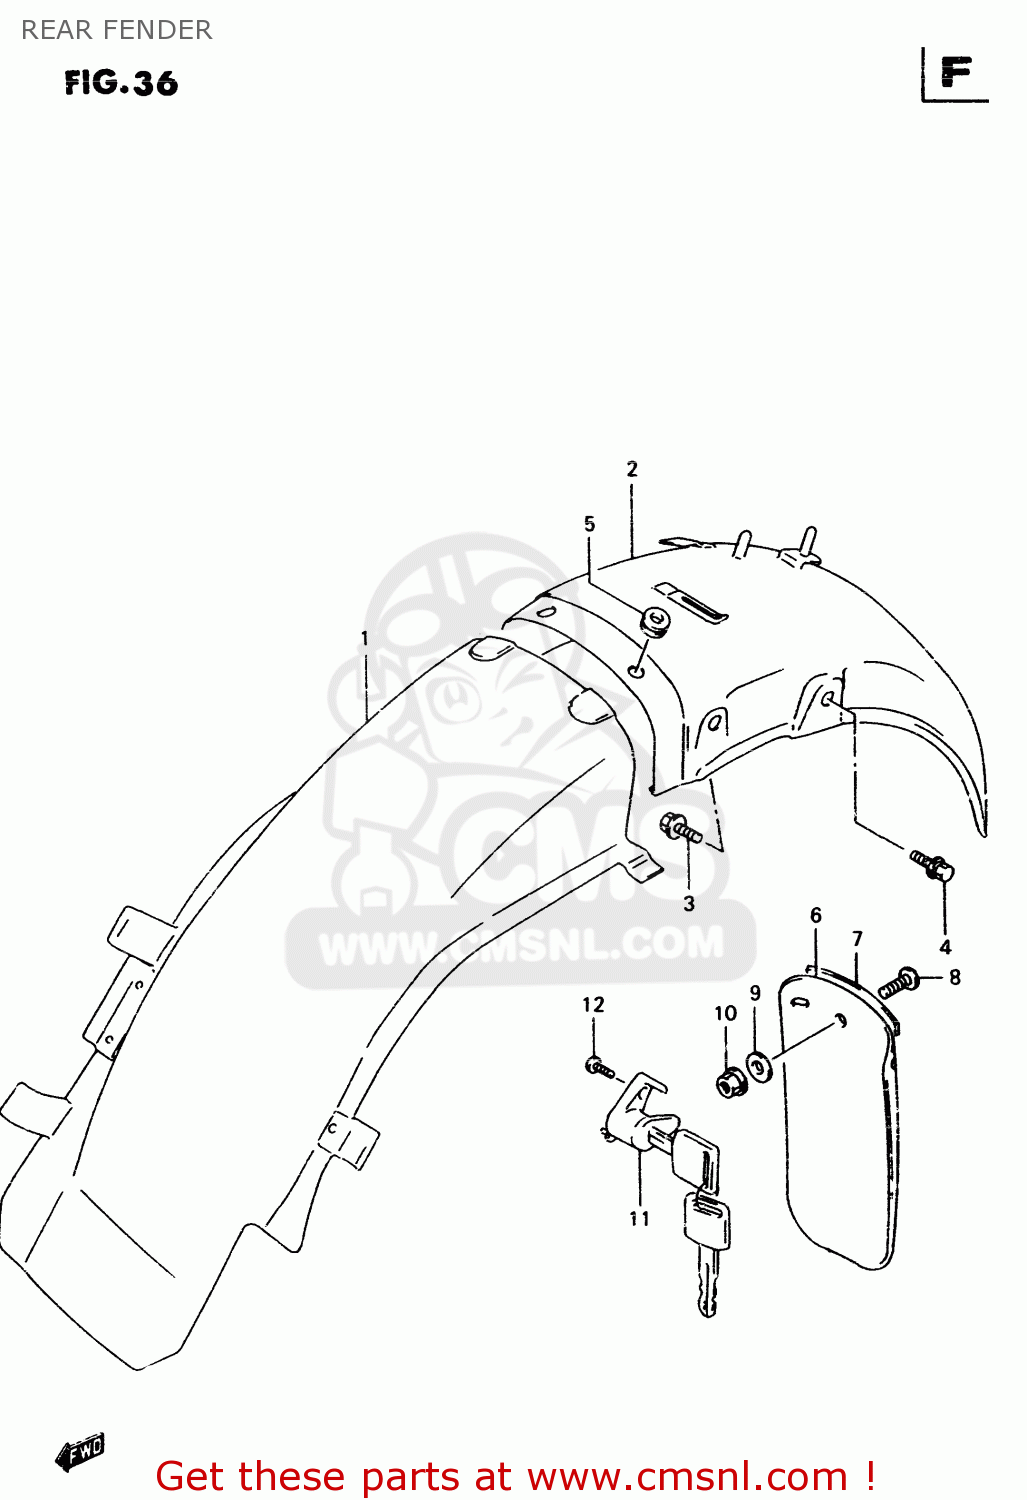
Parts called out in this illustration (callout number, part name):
1	BODY, REAR FENDER FRONT
2	FENDER COMP,RR
3	BOLT
4	BOLT
5	CUSHION
6	MUDFLAP,RR FENDER
7	CUSHION,RR FENDER EXTENSION
8	SCREW
9	WASHER(6.5X18X1.6)
10	NUT 6MM
11	LOCK SET,HELMET
12	SCREW
